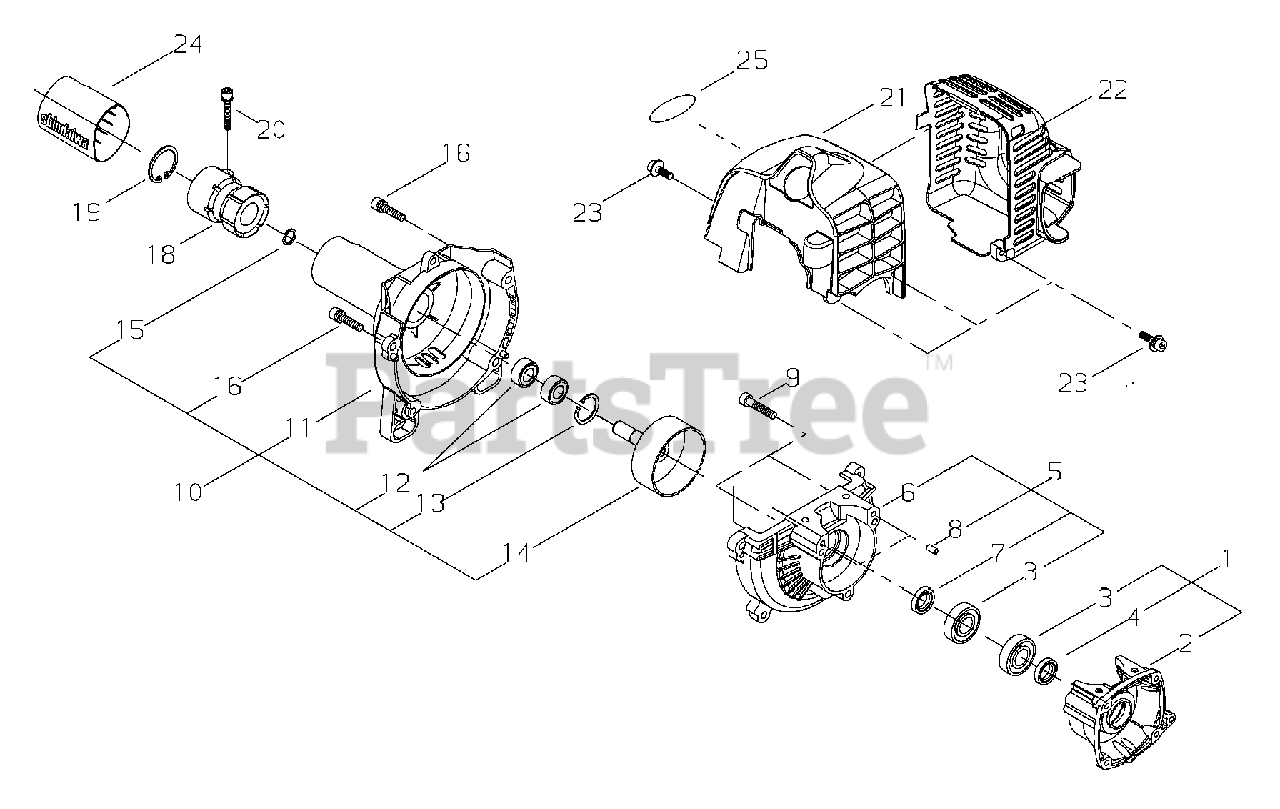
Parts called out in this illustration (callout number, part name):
1	CRANKCASE ASSY, S
2	CRANKCASE S
3	BEARING, BALL 6001 C3
4	SEAL, OIL 12
5	CRANKCASE ASSY, M
6	CRANKCASE M
7	SEAL, OIL 12
8	PIN, LOCATING Ø4×8
9	BOLT 5×25
10	FAN CASE ASSY
11	COVER, FAN
12	BEARING, BALL 6000 DDU
13	RING, SNAP Ø26
14	DRUM, CLUTCH
15	RING, SNAP WR10
16	BOLT M5×16
18	CUSHION, AV
19	RING, SNAP Ø40
20	BOLT M5×22
21	COVER, ENGINE
22	COVER, MUFFLER
23	BOLT M4×16
24	PROTECTOR
25	LABEL - MODEL 242
